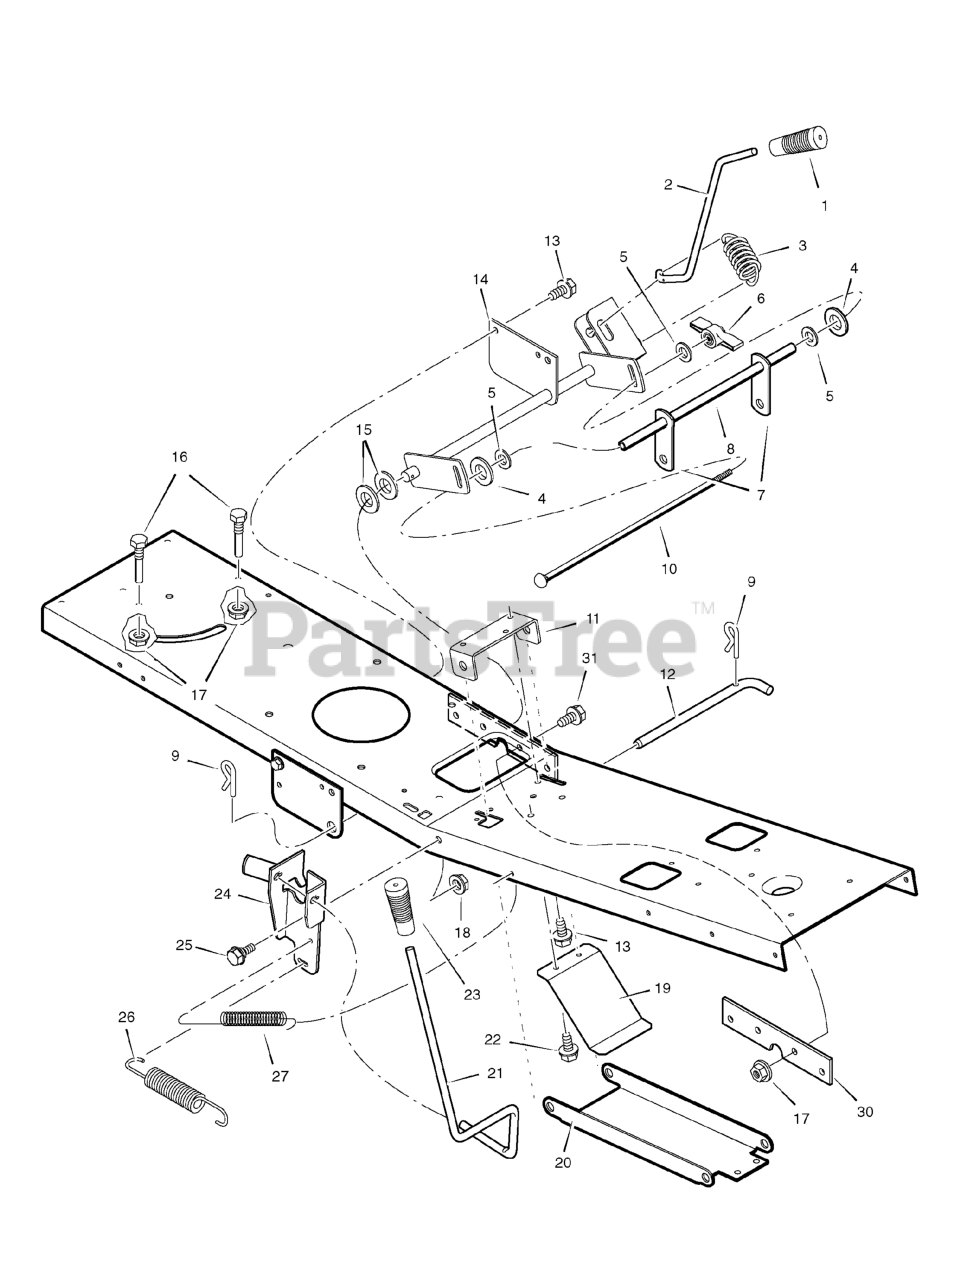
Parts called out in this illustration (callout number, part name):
1	Grip, Lift Lever
2	Lever, Lift
3	Spring, Extension
4	Pad, Friction
6	Wingnut
8	Tube, Spacer
9	Pin, Hair
10	Bolt, Carriage
11	Bracket, Front Hanger Pivot
12	Pin, Front Hanger
14	Arm Assembly, Lifter
16	Screw, Guide
17	Nut, Flange
18	Nut, Flange
19	Spring, Leaf
20	Hanger, Front
21	Lever, PTO
23	Grip, PTO
24	Bracket, PTO
25	Bolt, Shoulder
26	Spring, Extension
27	Spring, Extension
30	Plate, Reinforcement
